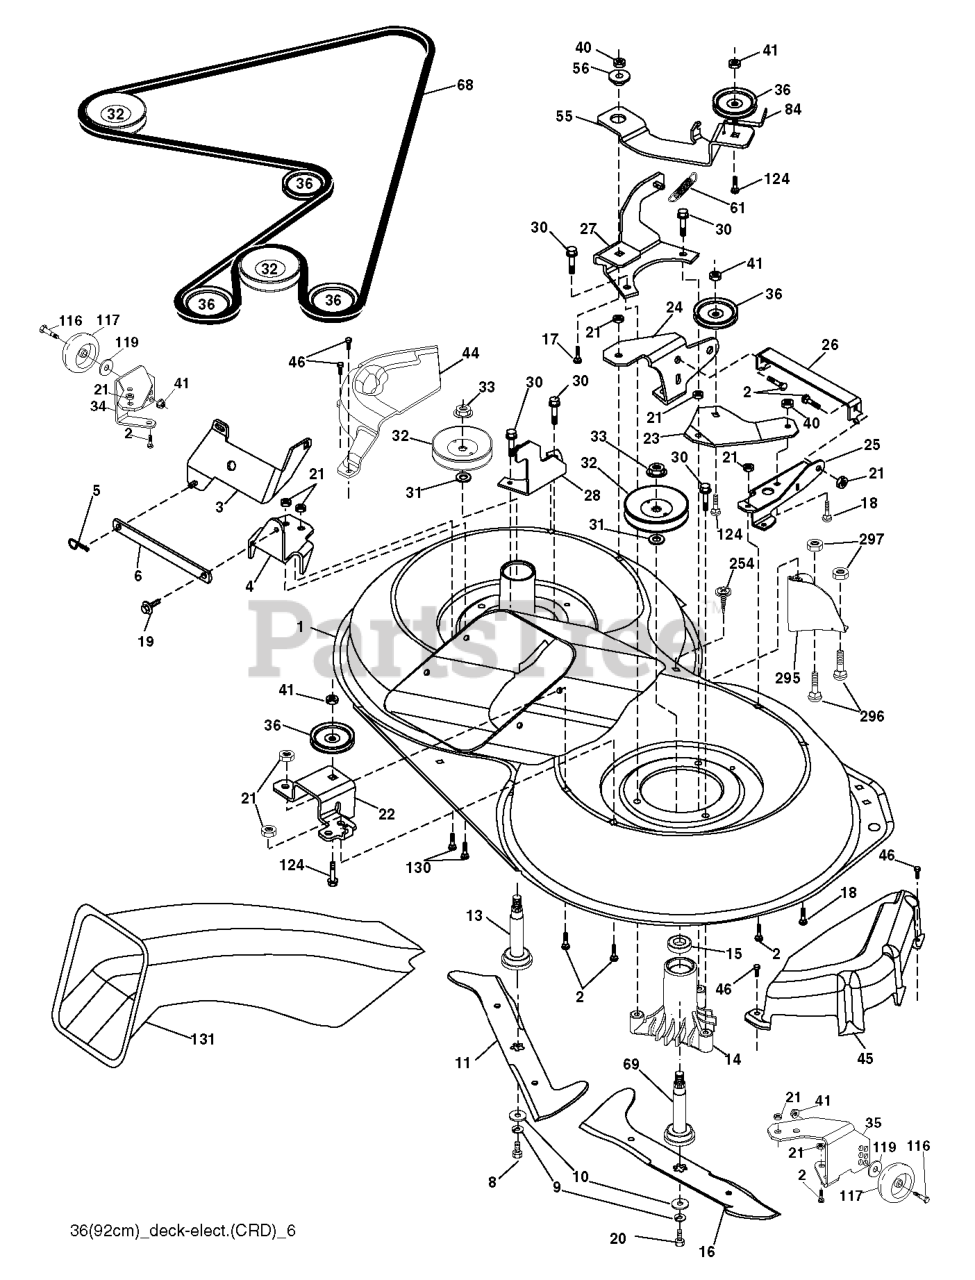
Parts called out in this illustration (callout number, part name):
2	RP BOLT 5/16-18 X3/4 ZN/YEL GR
5	RETAINER-SPRNG RB
6	BAR.SWAY.92.CRD
8	BOLT.3/8-24X1.25 GR8
9	LOCKWASHER
10	WASHER.BLADE
13	SHAFT ASM VENT
14	HOUSING.MANDREL.VENTED (MACHD)
17	BOLT.3/8-14X1.25
19	BOLT SHD 5/16-18
20	BOLT.3/8-24X1.25GR8. LHTHRD
21	LOCKNUT
26	SUPPORT
30	SCREW, WASHER HEAD
31	WASHER.SPACER.MANDREL
32	PULLEY MANDREL
33	NUT.FLANGE.LOCK.TOP
36	PULLEY.IDLER.4.25
41	NUT LOCK FLG 3/8-16 UNC
45	COVER.MANDREL.RH.CRD
46	SCREW.1/4-20X5/8
55	ARM.IDLER.92 CRD.2006
56	SPACER.RETAINER.MOWER
61	SPRING
68	BELT.DRIVE.92CM.CRD.2006
69	SHAFT.ASM.W/LWR.BRG.RH.THREAD
84	KEEPER, BELT IDLER
116	BOLT.SHOULDER.3/8-16X3-5/8.
117	RP WHEEL. GUAGE RALLY
119	WASHER
124	BOLT.3/8-16X1.50
130	BOLT.CARR.SQNK.5/16-18UNC.X3/4
131	CHUTE BAGGER
254	SCREW 3/8-16X1
296	BOLT
297	NUT CENTERLOCK
